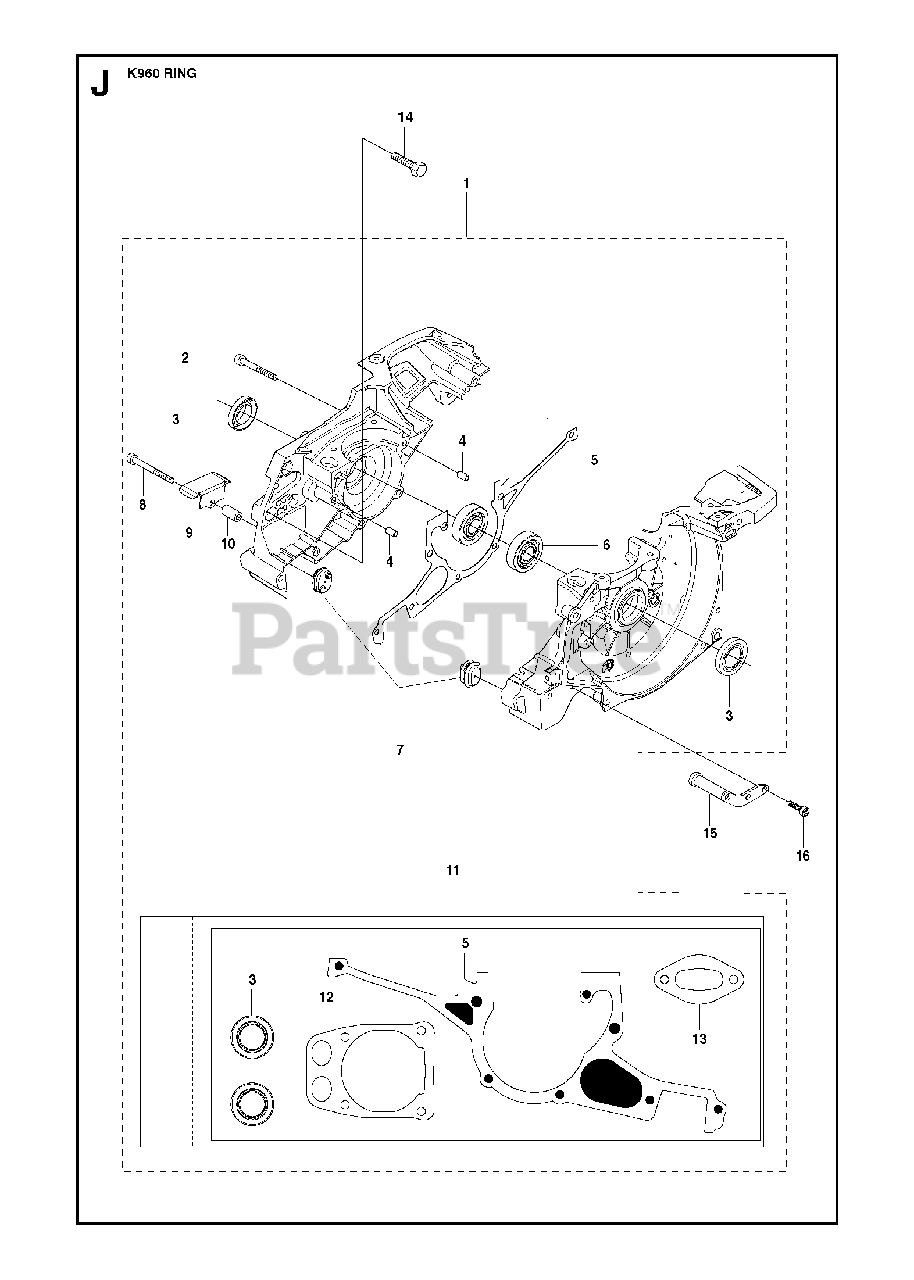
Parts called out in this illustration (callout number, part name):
1	CRANKCASE ASSYIncl. 2 - 8
2	SCREW ITXSCM
3	SEALING RINGGasket kit 11
4	GUIDE BUSHING
5	GASKETGasket kit 11
6	BALL BEARING
7	RUBBER BUSHING
8	SCREW ITXSCM
11	GASKET KITIncl. 3, 5, 12, 13
12	GASKET
13	GASKET
